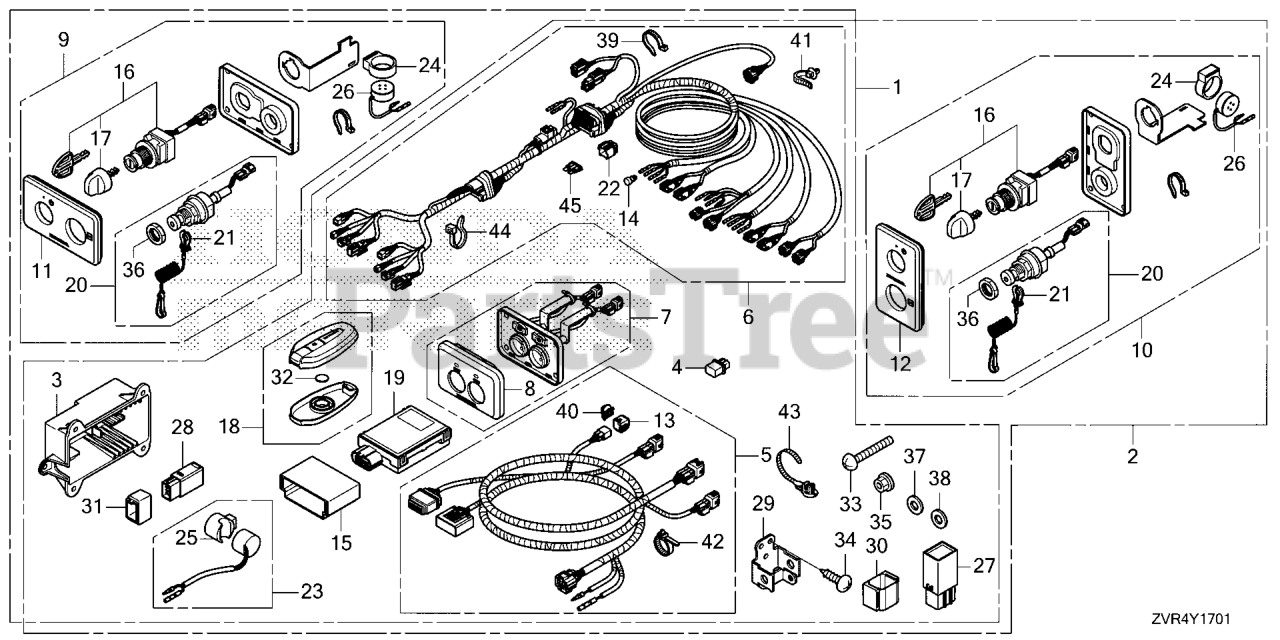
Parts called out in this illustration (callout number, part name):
1	UNIT KIT, SMART KEY
2	UNIT KIT, SMART KEY
3	CASE, CONTROL UNIT (SMART)
4	TERMINATOR ASSY.
5	HARNESS ASSY., SMART KEY CONTROL
6	HARNESS, SMART KEY
7	PANEL ASSY., START STOP (TWIN)
8	PANEL, START STOP (TWIN)
9	PANEL ASSY., KEY SWITCH (SMART)
10	PANEL ASSY., KEY SWITCH (SMART)
11	PANEL, KEY SWITCH
12	PANEL, KEY SWITCH
13	CAP, DUMMY (WPC 4P 090 M) (RED)
14	PLUG, CONNECTOR (INNER) (TROLLING CONTROL)
15	SUSPENSION, CONTROL UNIT (SMART)
16	SWITCH ASSY., COMBINATION (SMART)
17	KNOB
18	FOB ASSY. (315MHZ) (NOT AVAILABLE)
19	CONTROL UNIT, SMART (315MHZ)
20	SWITCH ASSY., EMERGENCY STOP
21	WIRE, EMERGENCY
22	COVER ASSY., FUSE (10A)
23	BUZZER ASSY., WARNING
24	SUSPENSION, AUDIBLE PILOT
25	SUSPENSION, WARNING BUZZER
26	BUZZER, WARNING
27	RELAY, WATERPROOF (15AX2)
28	RELAY ASSY., MAIN
29	BRACKET, MAIN RELAY
30	CUSHION, RELAY
31	SUSPENSION, RELAY
32	BATTERY (CR2025) (MSDS)
33	SCREW, PAN (5X40) DUAL QTY = (8) (SINGLE)
34	SCREW, TAPPING (5X16) (PO)
35	NUT, FLANGE (5MM)
36	NUT
37	WASHER, PLAIN (5MM)
38	WASHER, SPG (5MM)
39	HOLDER, CONNECTOR (128.6MM) (NATURAL)
40	CLIP, CONNECTOR (DARK BROWN)
41	CLIP, HARNESS BAND (155.3MM) (BLACK)
42	CLIP, HARNESS BAND (145MM) (BLACK)
43	CLIP, BAND HARNESS (152.4MM) (BLACK)
44	BAND, CABLE (NATURAL)
44	BAND, HARN
45	FUSE, BLADE (10A)
